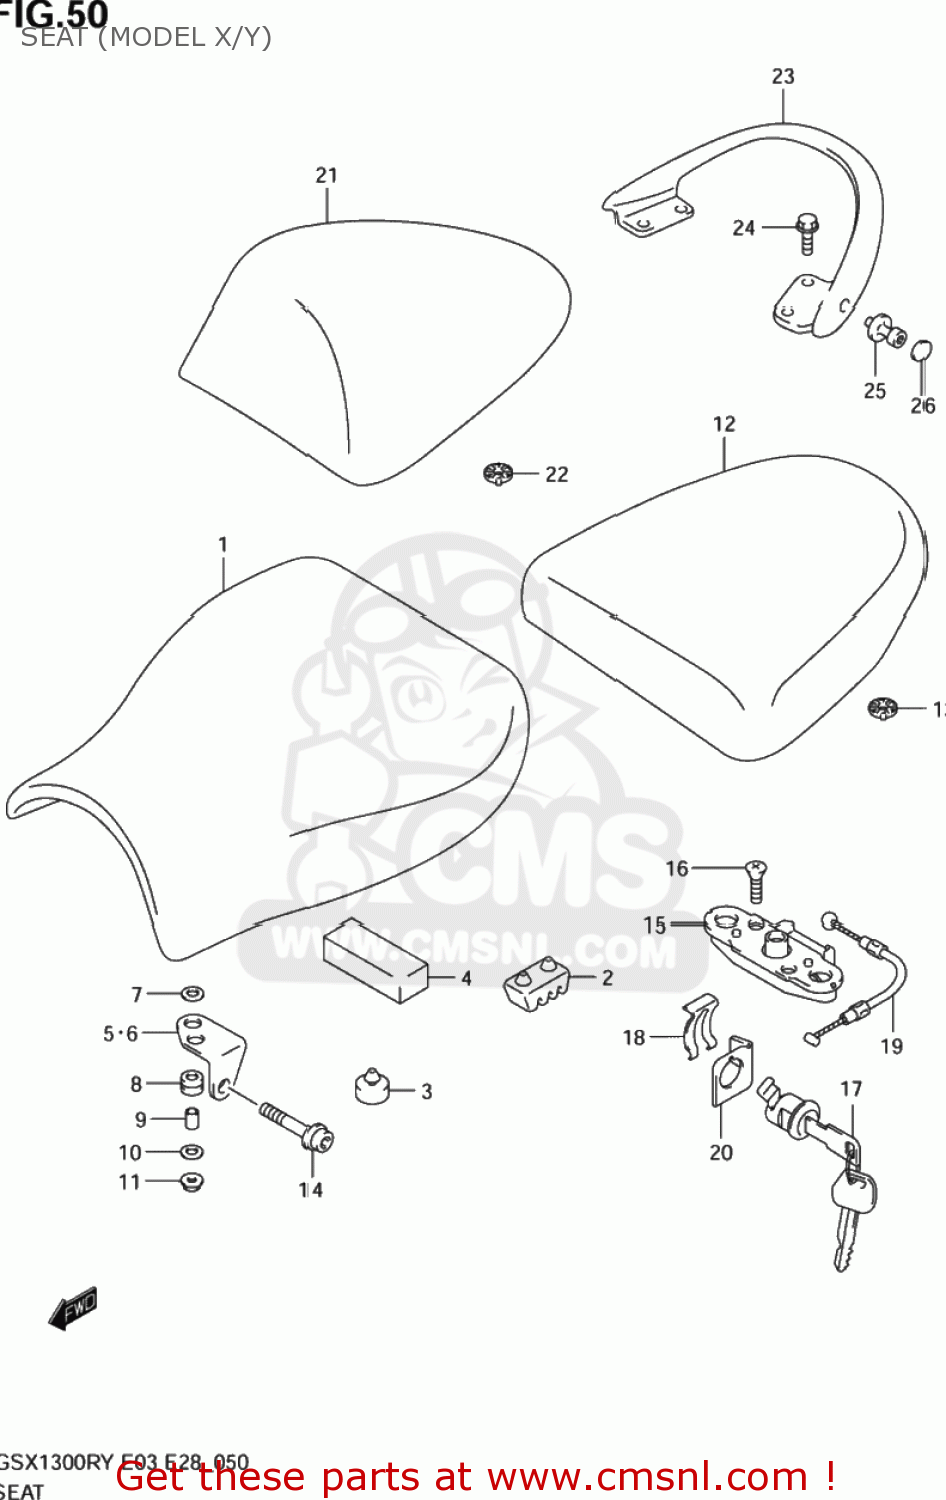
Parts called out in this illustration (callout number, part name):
1	SEAT ASSEMBLY
2	CUSHION,SUPPORT(50X25X32)
3	CUSHION
4	CUSHION,CTR
5	BRACKET,SEAT FR,R
6	BRACKET,SEAT FR,L
7	WASHER(6.5X20X1.6)
8	CUSHION,SEAT 10X20X10
9	SPACER(6.5X10X10)
10	WASHER(6.5X20X1.6)
11	NUT
12	SEAT ASSEMBLY,PILLION
13	CUSHION
14	BOLT,SEAT FR
15	BRACKET,SEAT SUPPORT,RIGHT
16	SCREW
17	LOCK SET,SEAT
18	PLATE,SEAT LOCK ASSY
19	CABLE,SEAT LOCK
20	GUIDE,SEAT LOCK CABLE
21	BOX COMP,SEAT TAIL
22	CUSHION
23	HANDLE,PILLION RIDER
24	BOLT
25	HOOK,PILLION RIDER HANDLE
26	CAP(OD:10)
